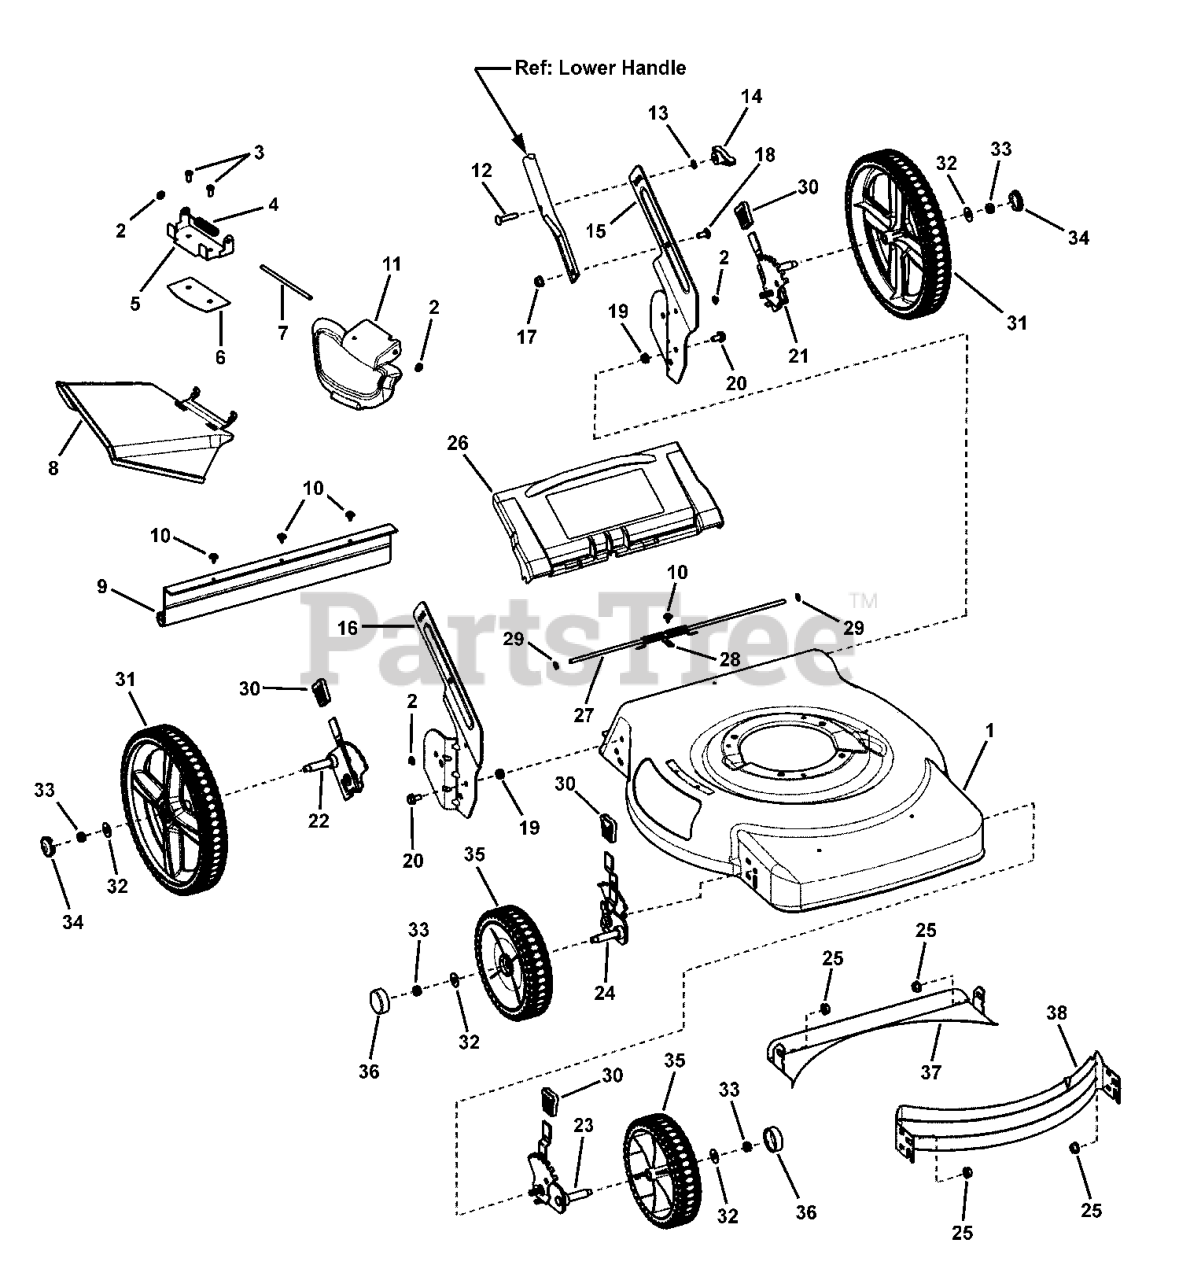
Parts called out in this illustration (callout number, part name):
1	DECK, 22" Walk, Push
2	PUSHNUT, 1/4"
3	SCREW, PHST, Torx, 1/4-20 X .550"
4	SPRING, Torsion, Chute
5	BRACKET, Chute
6	PLATE, Mulch 22 RB Scotts
7	ROD, Chute Pivot - 1/4 dia. x 5.55"
8	SIDE CHUTE, Plastic, Black
9	GUARD, Rear
10	SCREW, #10-24 x 1/2 Hex Washer Self-Tap - Sems
11	COVER, Mulch, Plastic, Black
12	BOLT, RHSN, 5/16-18 X 1 GR5 YZ
13	WASHER, Internal Tooth Lock, 5/16
14	KNOB, 5/16-18 Wing Nut
15	BRACKET, Lower Handle, LH
16	BRACKET, Lower Handle, RH
17	NUT, HFL, 5/16-18 BZ
18	BOLT, RHSSN, 5/16-18 X 3/4 GR5 YZ
19	NUT, 3/8-16 Hex Center Lock YZ
20	BOLT, 5/16-18 x 5/8 Hex Flange Lock
21	ASSY, HOC, Left Rear, 9 Position
22	ASSY, HOC, Right Rear, 9 Position
23	ASSY, HOC, Left Front, 9 Position
24	ASSY, HOC, Right Front, 9 Position
25	NUT, 3/8-16, Hex Flange Lock, GR 5
26	DOOR, Rear Discharge, 22 Walk Mower
27	ROD, Pivot, Rear Door - 1/4 dia. x 17-1/2 YZ
28	SPRING, Torsion, Rear Door, 22 Walk Mower
29	RETAINER, Push On, 1/4"
30	GRIP, Height Latch
31	WHEEL,12" X 2" Idle, W/DB TRD, Brute
32	WASHER, Flat, 1 O.D. x .382 I.D.
33	NUT, 5/16-18 Hex Flange Lock BZP
34	HUBCAP, 12" Wheel, Black
35	WHEEL, 8" X 2" Idle, W/DB TRD, Brute
36	HUBCAP, Round, Black
37	BAFFLE, Rear, 22" Deck
38	BAFFLE, Front, 22" Walk Mower
